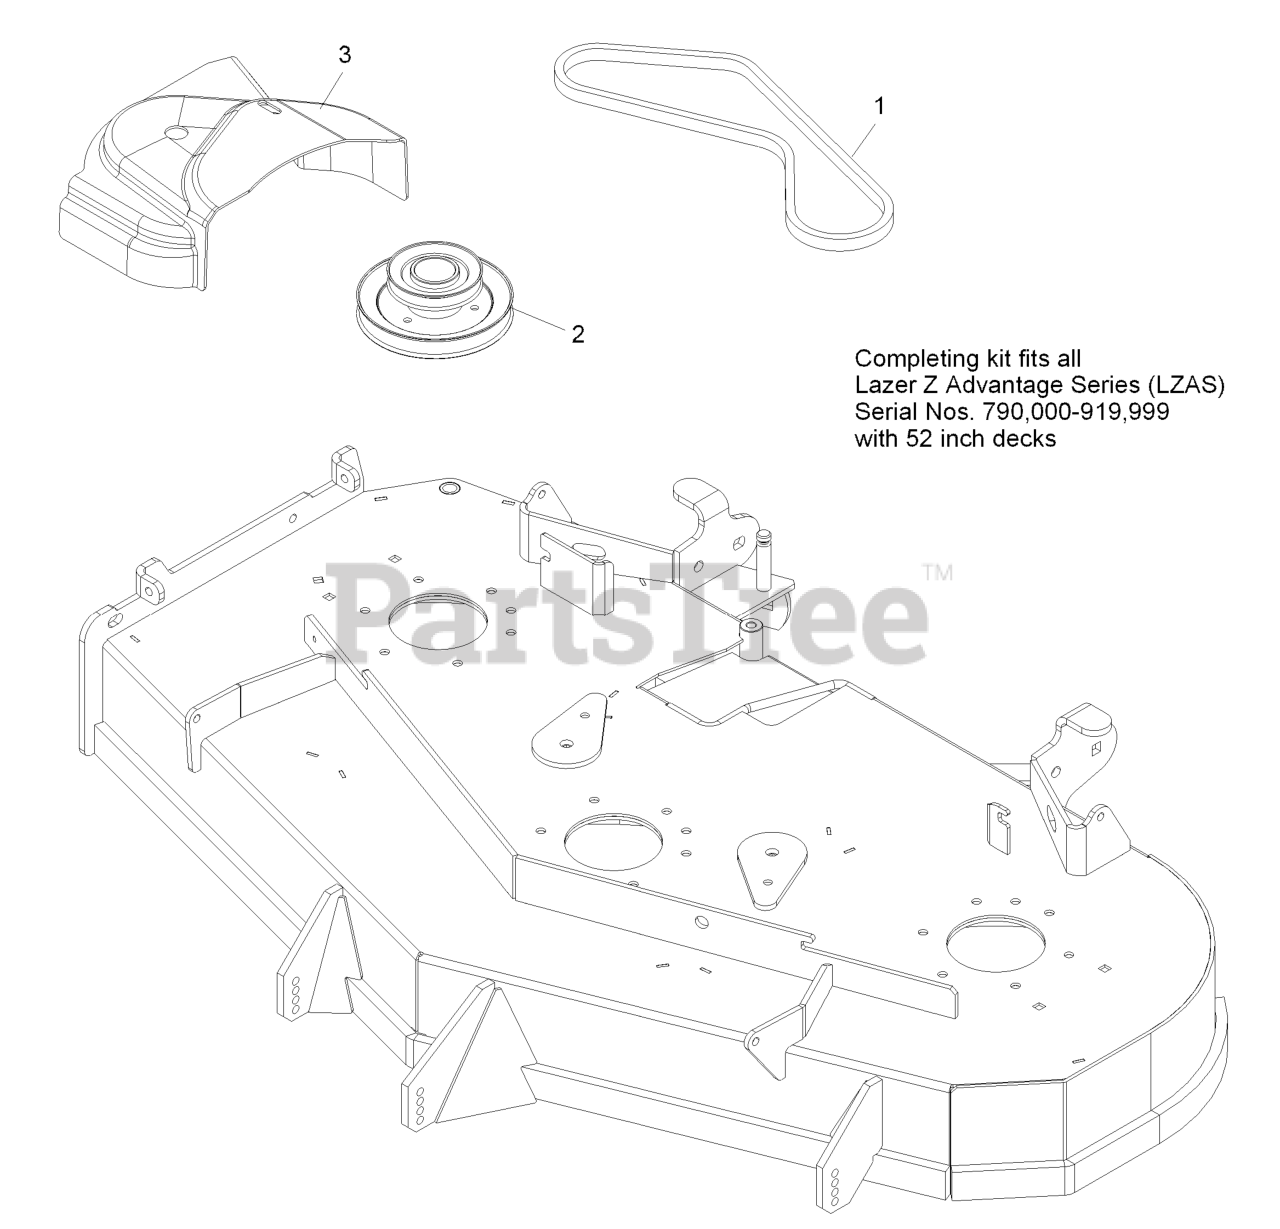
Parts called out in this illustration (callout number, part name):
1	BELT, BLOWER 52"DECK
2	JACKSHAFT,UV DRIVE 524
3	COVER,BELT UV 52
